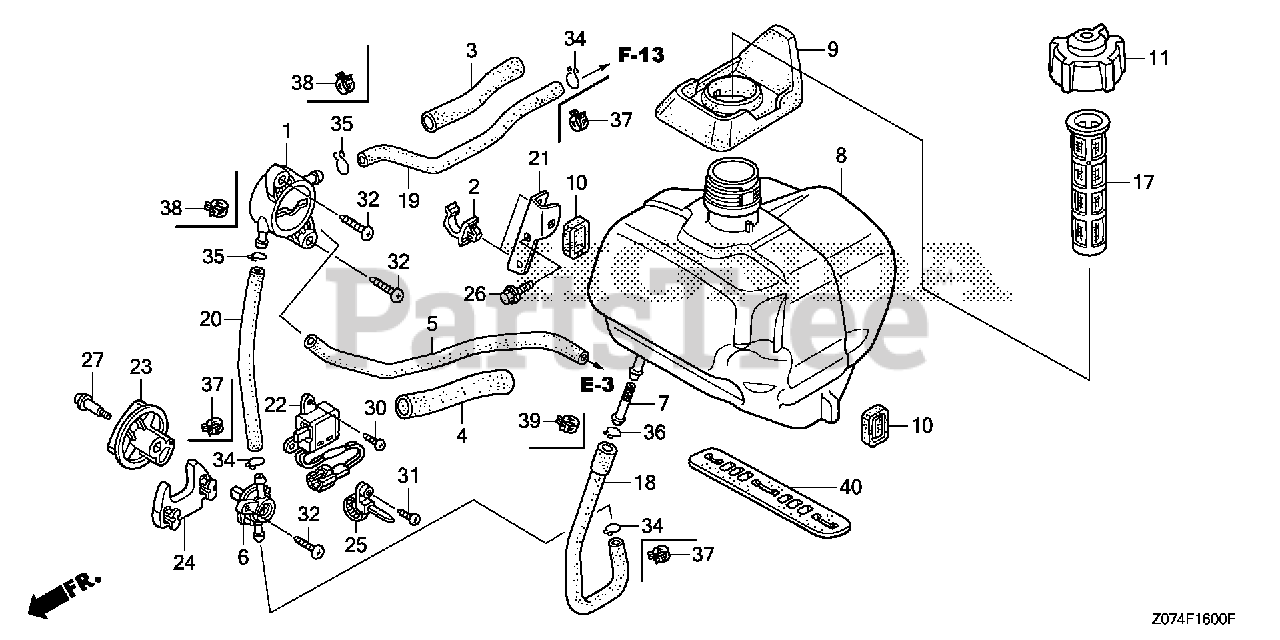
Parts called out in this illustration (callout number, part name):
1	PUMP ASSY., FUEL (MSDS)
2	CLIP, TUBE
3	RUBBER A, SUPPORTER
4	RUBBER B, SUPPORTER
5	TUBE, DIAPHRAGM
6	PETCOCK ASSY.
7	FILTER, FUEL
8	TANK, FUEL
9	SEAL, FUEL FILLER NECK
10	RUBBER A, TANK MOUNTING
11	CAP ASSY., FUEL TANK
12	INNER, FUEL CAP (NOT AVAILABLE)
13	SPONGE, FUEL CAP BREATHER
14	GASKET, FUEL CAP
15	VALVE, BREATHER
16	SPRING, FUEL CAP
17	FILTER, FUEL
18	TUBE, FUEL TANK (FKM)
18	TUBE, FUEL TANK
19	TUBE A, FUEL (FKM)
19	TUBE A, FUEL
20	TUBE B, FUEL (FKM)
20	TUBE B, FUEL
21	BRACKET, FUEL TUBE
22	SWITCH ASSY., ENGINE STOP
23	KNOB, ENGINE SWITCH
24	PLATE, ENGINE SWITCH
25	BAND, HARNESS
26	BOLT, FLANGE (6X12) (CT200)
27	SCREW, PAN (4X19)
28	WASHER (6MM)
29	O-RING (13.8X2.4) (N/A: SEE ASSEMBLY)
30	SCREW, TAPPING (3X12)
31	SCREW, TAPPING (3X16)
32	SCREW, TAPPING (5X20) (PO)
33	PIN, LOCK (6MM)
34	CLIP, TUBE (B8)
35	CLIP, TUBE (B10)
36	CLIP, TUBE (C11)
37	CLIP, TUBE (D8)
38	CLIP, TUBE (D8.5)
39	CLIP, TUBE (10.5MM)
